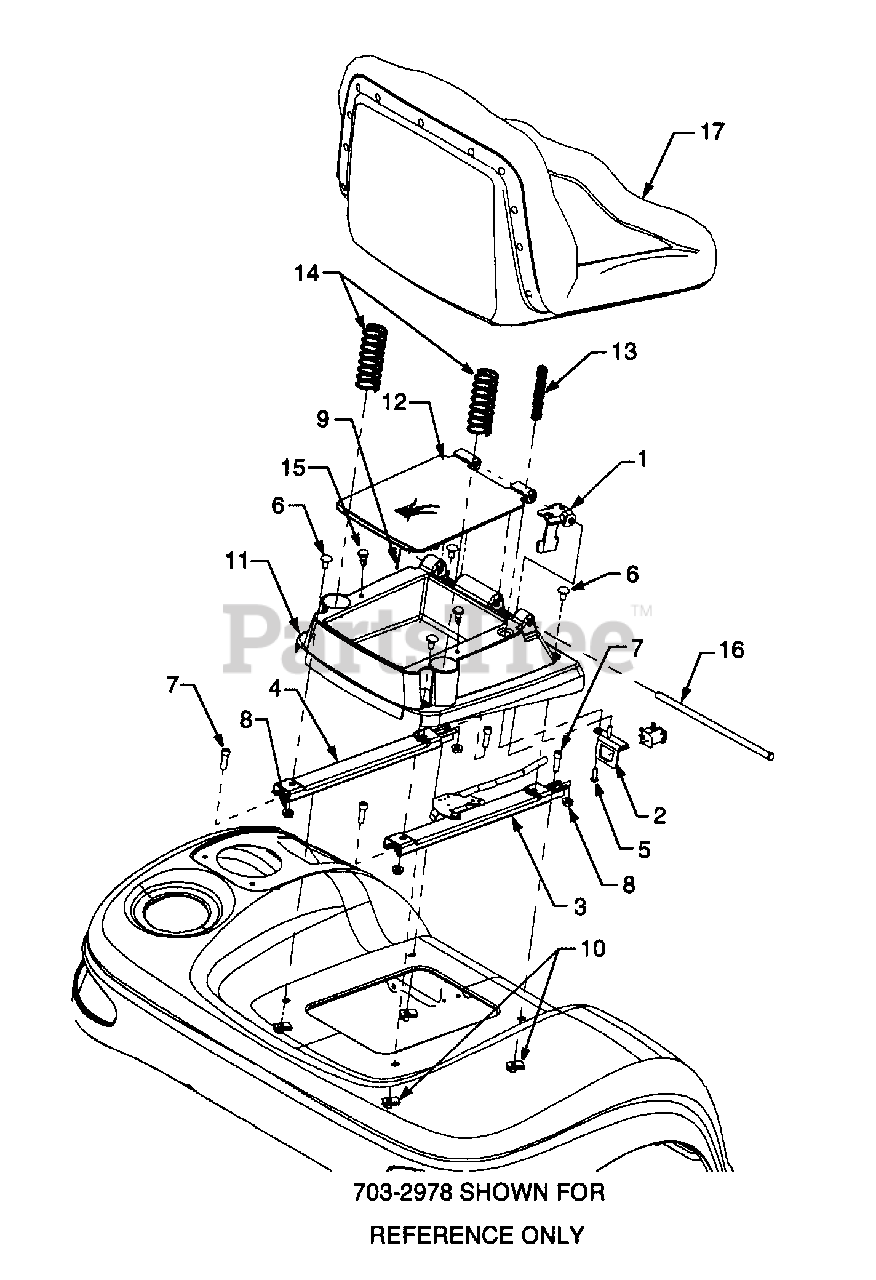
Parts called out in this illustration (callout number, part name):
1	Bracket, Seat Switch
2	Bracket, Switch Mounting
3	Track, Seat, w/Latch
4	Track, Seat, w/o Latch
5	Screw, Pan Torx Hd., #12-14 x .5
6	Carriage Bolt, 5/16-18 x .62
7	Screw, Pan Torx Hd. 5/16-18 x 1.0
8	Nut, Hex Flange Lock, 5/16-18
9	Pin, Cotter, 3/32 x .75
10	Speed Nut, U-Type, 5/16-18
11	Base, Seat
12	Lid, Tlbx
13	Spring, Compression
14	Spring, Compression
15	Bumper
16	Rod, Seat Pivot
17	Seat, High Back
